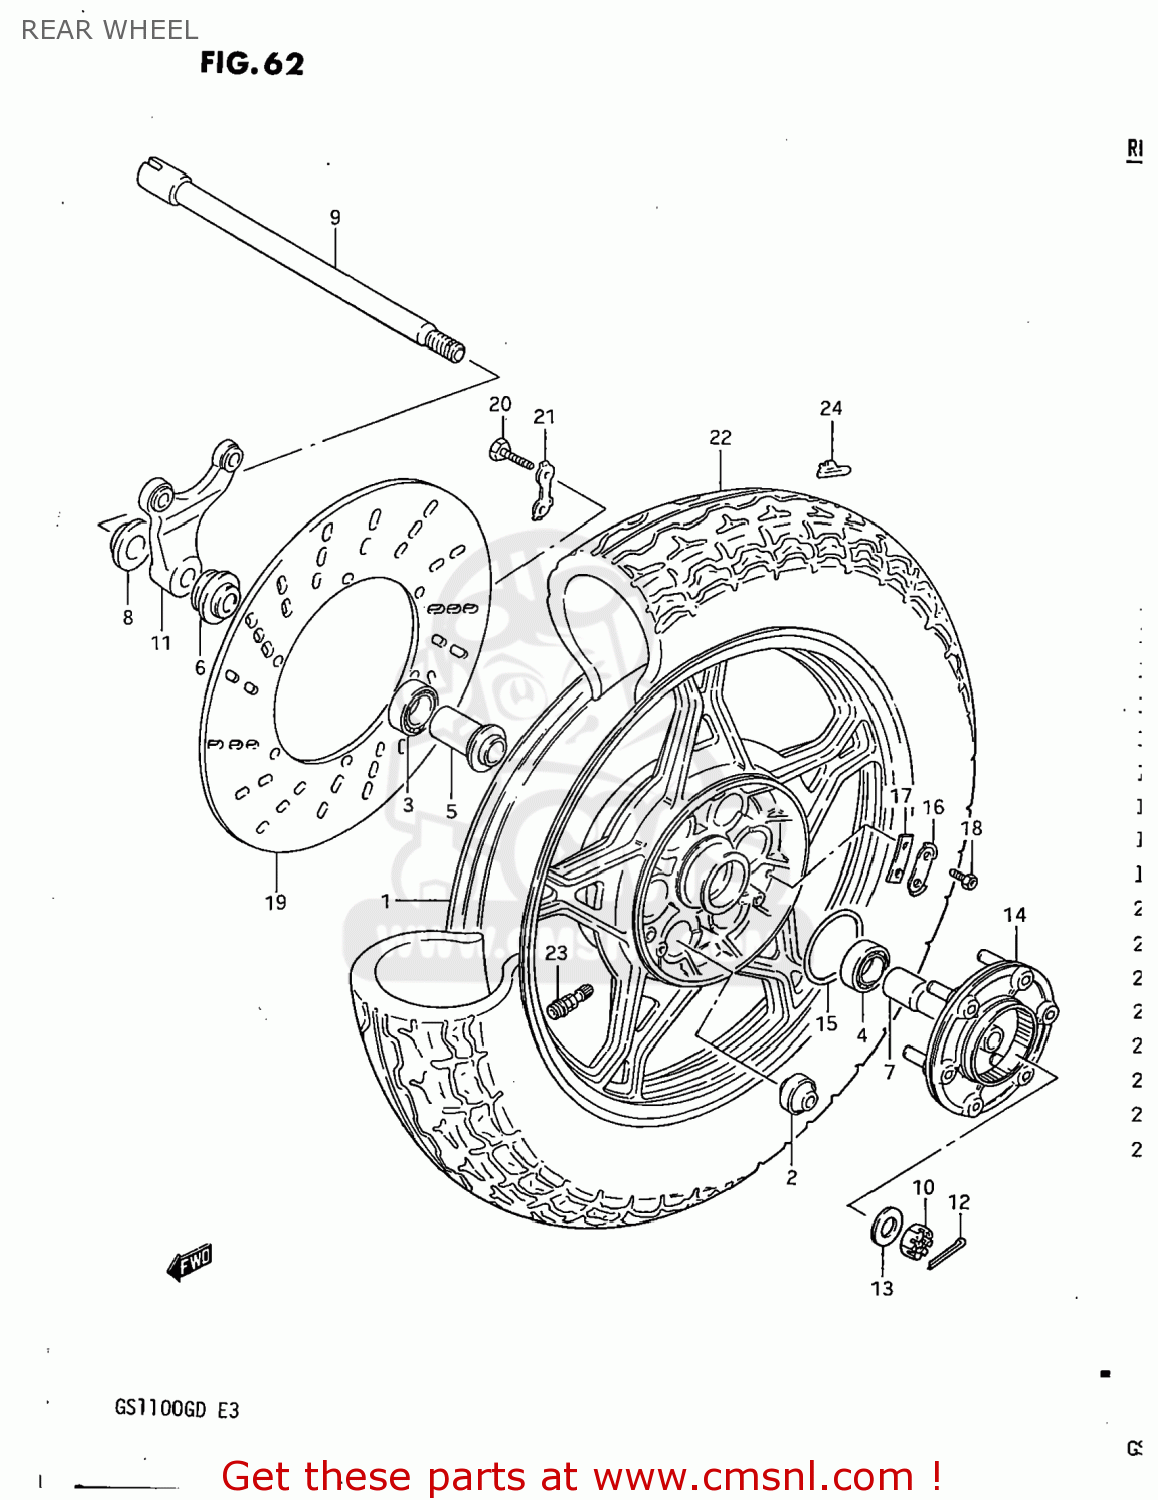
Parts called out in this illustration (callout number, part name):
1	CASTING WHEEL,REAR 2.50
2	BUSH
3	BEARING
4	BEARING
5	SPACER,REAR HUB BEARING
6	SPACER,REAR AXLE
7	SPACER,REAR AXLE,LEFT
8	SPACER,REAR AXLE,RIGHT
9	AXLE,REAR
10	NUT
11	BRACKET,RR,CALIPER
12	PIN,COTTER
13	WASHER (17.5X36X3.2)
14	JOINT ASSEMBLY,REAR HUB DRUM
15	O RING(D:2.1,ID:65)
16	WASHER
17	WASHER,THRUST(T:1.6)
18	SCREW
19	DISC,RR BRAKE
20	BOLT(8X25)
21	WASHER
22	TIRE
23	VALVE ASSEMBLY,WHEEL RIM,J
24	BALANCER,WHEEL
